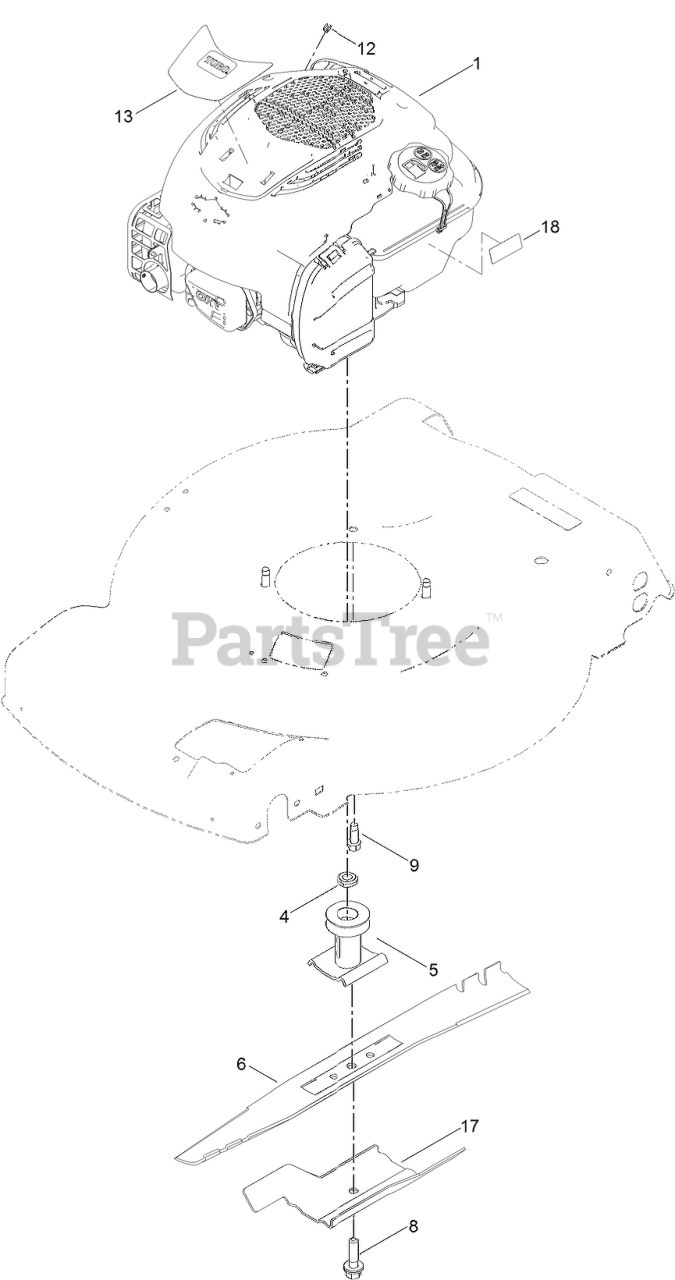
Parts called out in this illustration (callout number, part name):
4	SPACER-DRIVER
5	DRIVER-BLADE
8	BOLT-BLADE
9	SCREW-TAPTITE
12	STOP-ROPE
13	DECAL-SHROUD
17	ACCELERATOR-BLADE
18	DECAL-LEVEL, FUEL
